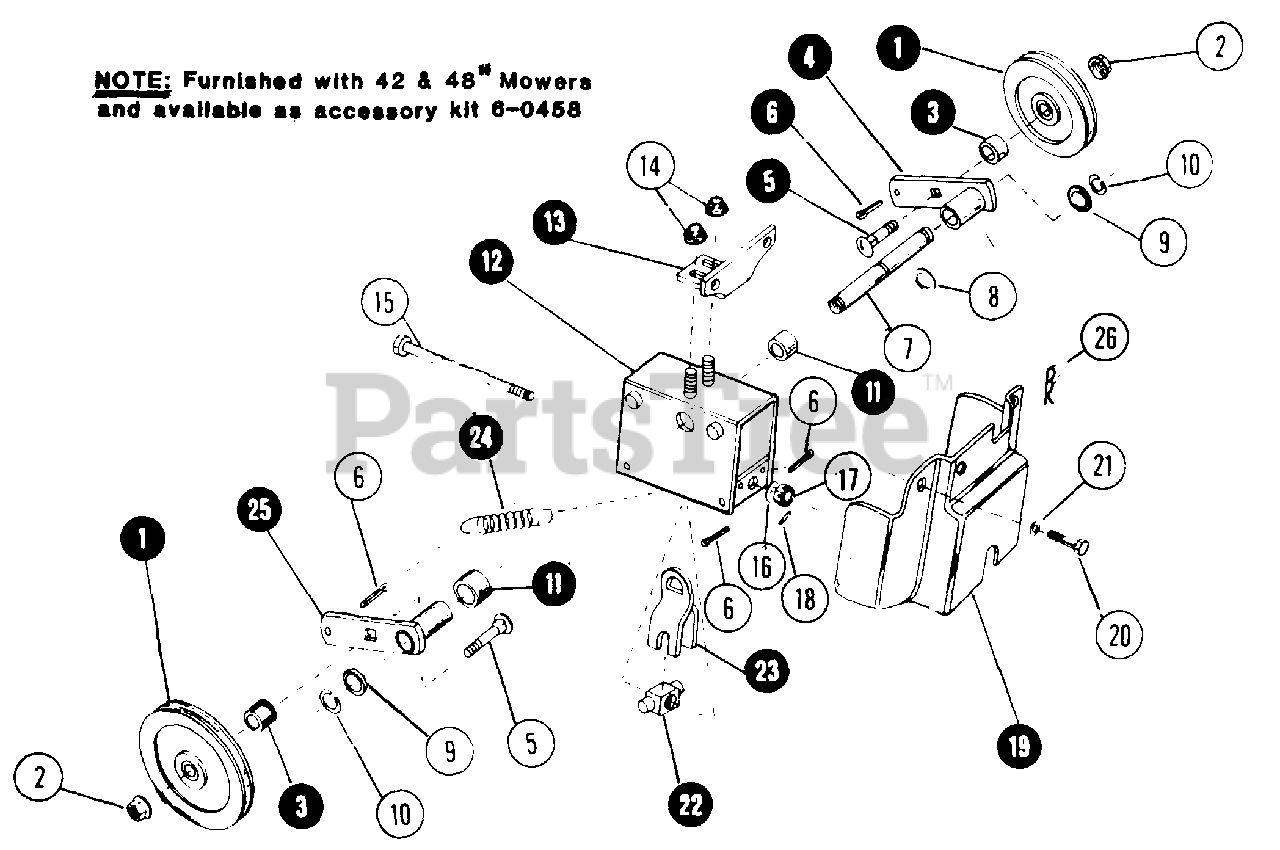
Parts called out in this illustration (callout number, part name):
1	PULLEY, IDLER
2	NUT, 1/2C FLANGE LOCK
3	SPACER, PULLEY
4	ARM, IDLER PULLEY LEFT SIDE
5	BOLT, 1/2C X 2 CARRIAGE
6	COTTER-PIN, 1/4 x 3/4
7	SHAFT, PULLEY RETAINER
8	WASHER, 17/32 x 7/8 x 5/64
9	SHIM, .009-.011"
10	RING, SHAFT RETAINER
11	SPACER, IDLER ARM PULLEY
12	FRAME, IMPLEMENT DRIVE
13	(NLA) BRACKET, MOUNTING
14	NUT, 3/8C FLANGE LOCK
15	BOLT, 3/8-16 x 5.5 HEX DRILLED (you must drill)
16	WASHER, 3/8" Flat
17	NUT, 3/8-16 HEX SLOTTED
18	PIN, SPIROL 3/32 x 9/16
19	COVER, IMPLEMENT DRIVE
20	BOLT, 5/16C x 7/8 HEX
21	WASHER, 5/16 FLAT
22	TRUNNION, PULLEY ADJUSTER
23	BRACKET, ADJUSTER
24	SPRING, IDLER PULLEY TENSION
25	ARM, IDLER PULLEY RIGHT SIDE
26	HAIR-PIN CLIP
